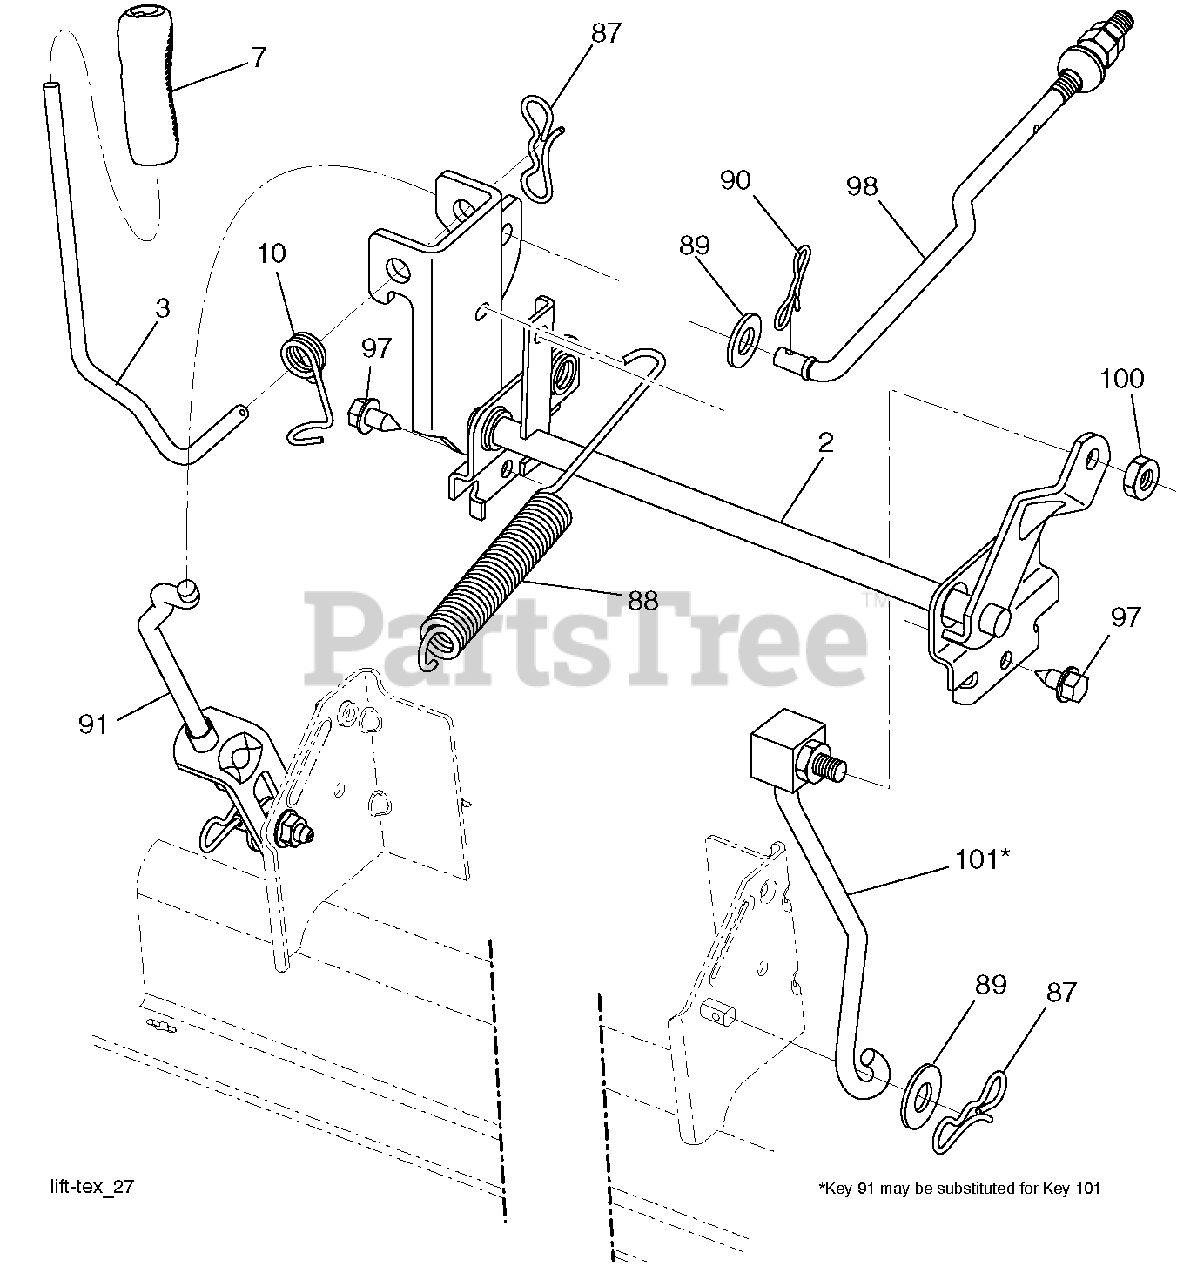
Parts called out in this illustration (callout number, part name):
2	SHAFT.ASM.CROSS.LIFT
3	LEVER.LIFT.HANDLE.GT
10	SPRING.TORSION.LIFT.HANDLE
87	PIN.COTTER.7/16.BOW TI
88	SPRING.LIFT.ASSIST.GT2
89	WASHER.CLEAR.ZINC
90	PIN.COTTER.5/16.BOW TI
91	LINK.ASM.LIFT.REAR
97	SCREW, 3/8-16X3/4
98	LINK.ASM.SUSP.FRONT.MW
100	LOCKNUT
101	LINK.ASM.LIFT.FIXE.38/42/46"
